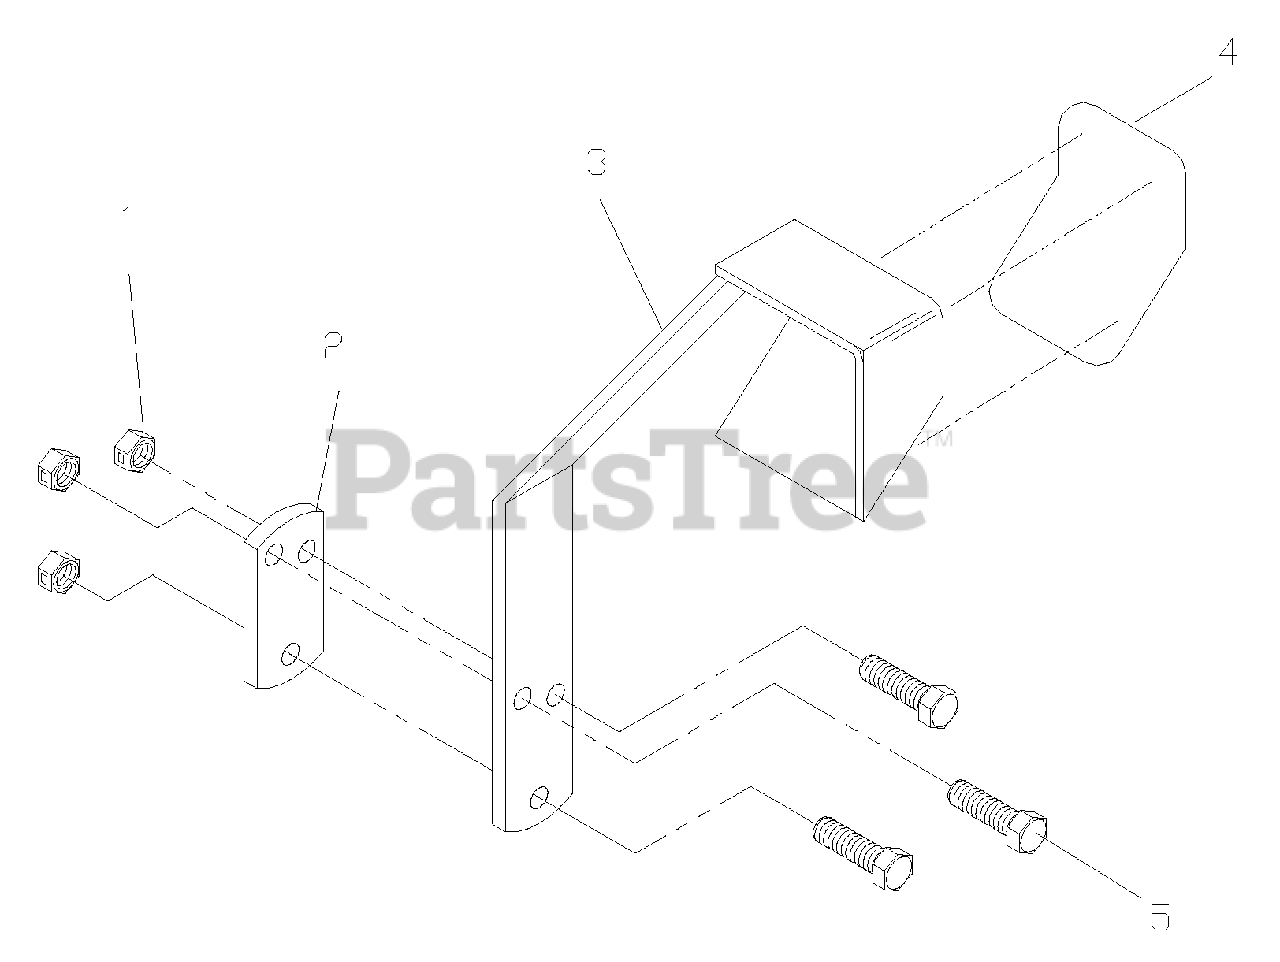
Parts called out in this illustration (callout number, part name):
1	NUT, 3/8C, NYLOC
2	PLATE, TIGHTING
3	PEDAL, LIFT
4	PAD, ANTI-SKID
5	HCS 3/8C X 1 1/2
